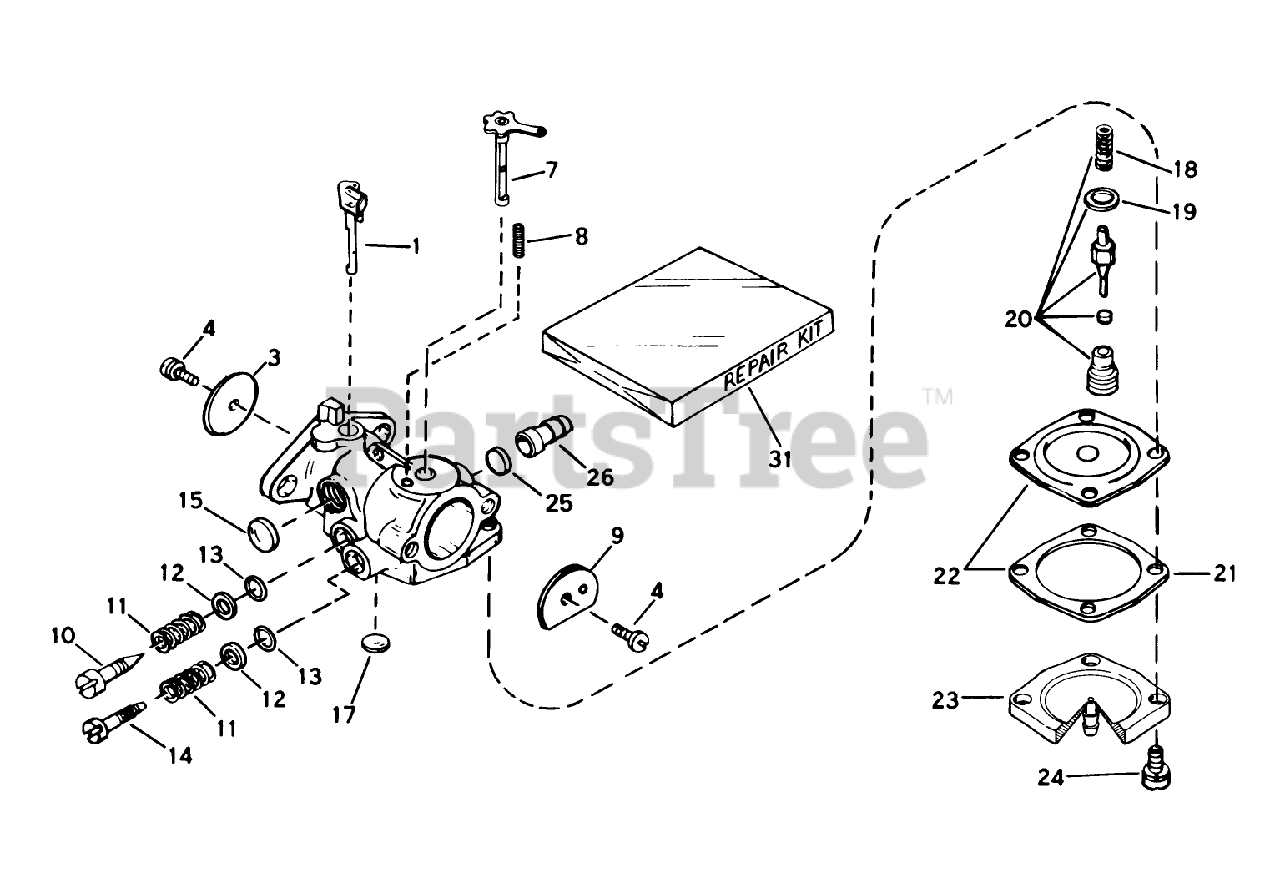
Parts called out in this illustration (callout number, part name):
1	Shaft/Lever-Throttle
3	Shutter-Throttle
4	Screw-Shutter
7	Shaft Lever Assembly
8	Spring-Positioning, Choke
10	Screw-Idle Adjustment
11	Spring
12	Washer
13	ORing
14	Screw Main Adjustment
15	Plug-Welch, Idle Mixture Well
17	Plug Welch
18	Spring-Valve
19	Gasket-Valve Seat
20	Inlet Needle, Seat, Spring Gasket Assy. (lncl. #1819)
21	Gasket-Diaphragm
22	Diaphragm Ass. (Incl. No. 21)
23	Cover-Diaphragm
24	Screw
26	Fitting-Fuel
31	Kit-Repair
